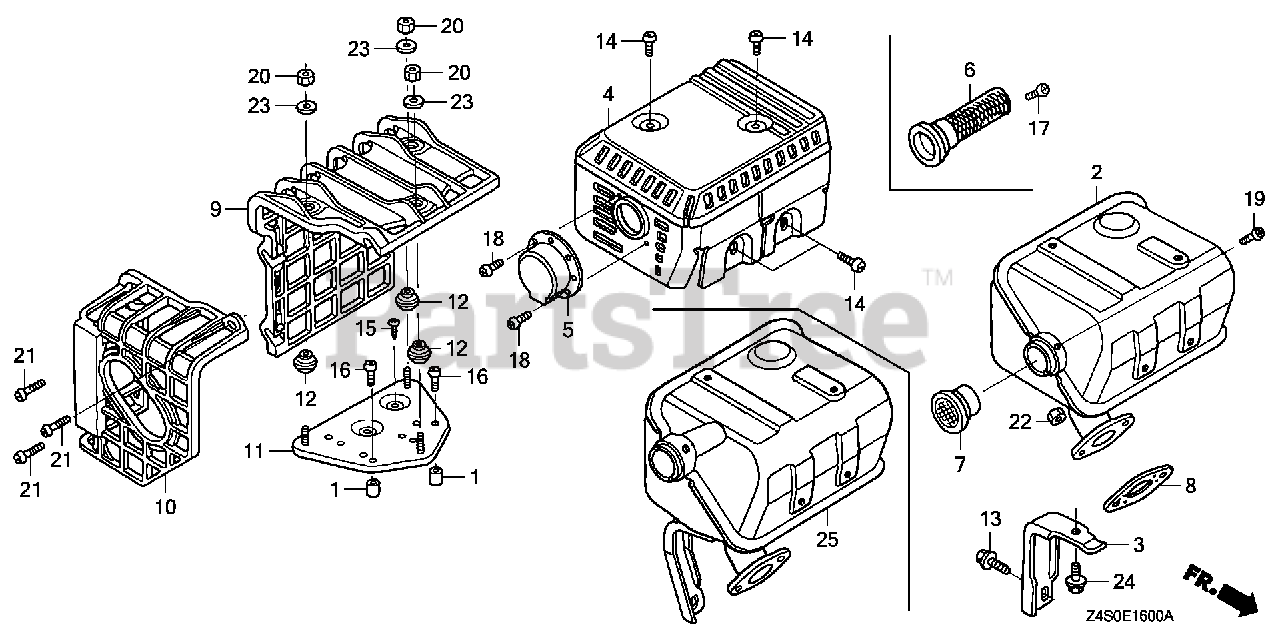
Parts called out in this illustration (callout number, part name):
2	MUFFLER (ARRESTER)
3	STAY, MUFFLER
4	PROTECTOR, MUFFLER
6	ARRESTER, SPARK
7	NETTING, WIRE FLANGE
8	GASKET, MUFFLER
13	BOLT, FLANGE (6X13)
14	SCREW, TAPPING (5X8)
17	SCREW, TAPPING (4X6) (TO INSTALL OPTIONAL SPARK ARRESTER)
19	SCREW, TAPPING (4X6)
22	NUT, HEX. (8MM)
24	BOLT, FLANGE (6X12) Use up to Engine SN 1543277.
